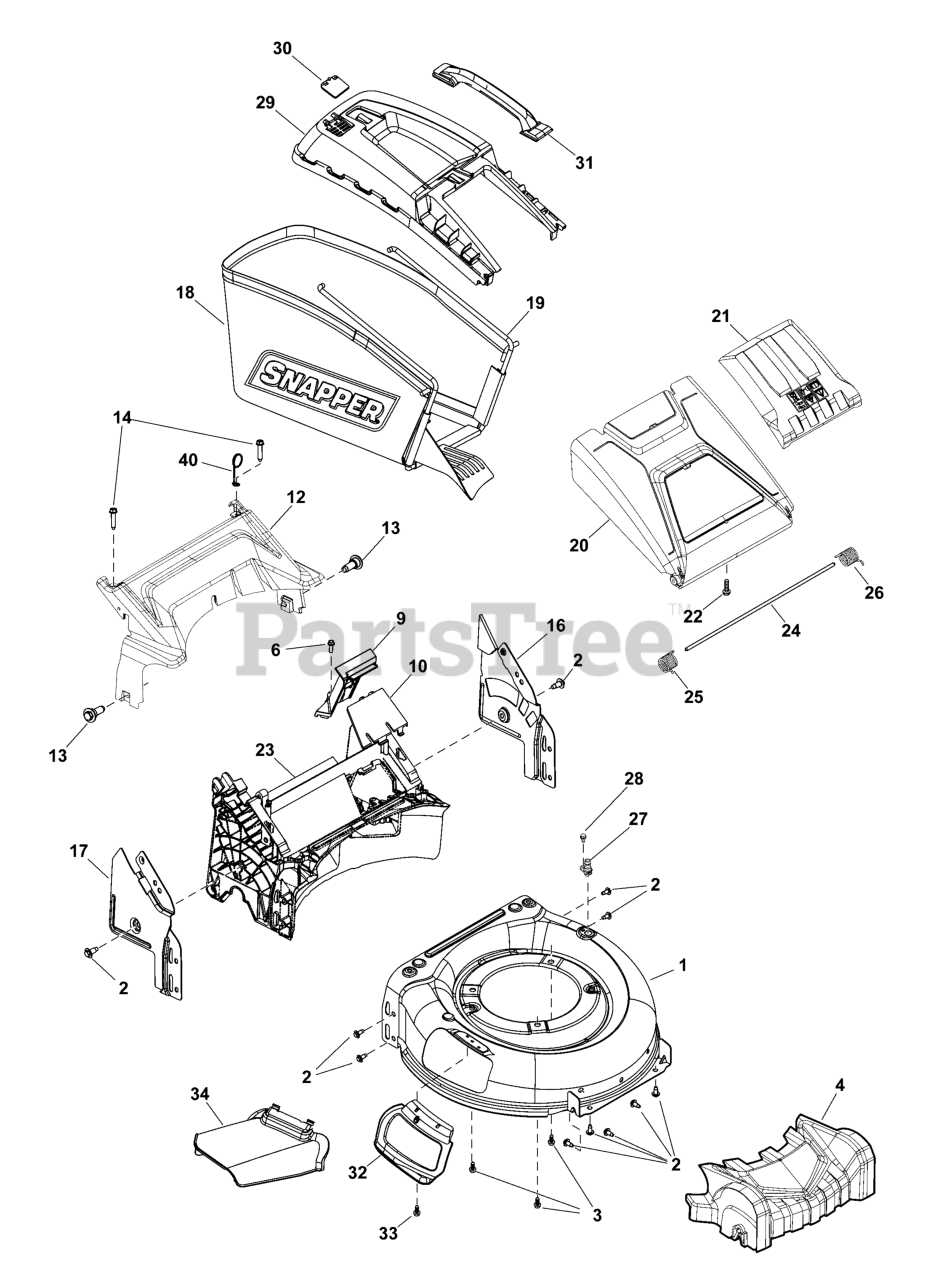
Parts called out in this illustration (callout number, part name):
1	DECK, NSP
2	SCREW, Hex Head
3	SCREW, Engine Mounting, 3/8-16 x 1
4	FRONT COVER, Deck
6	SCREW, 1/4-15X3/4, Self-Tapping, BZ
9	COVER, Rear
10	COVER, Front
12	COVER, Rear
13	SCREW, Hex Head
14	SCREW, 1/4-15 x 1-1/4
16	SUPPORT, Handle, LH
17	SUPPORT, Handle, RH
20	REAR FLAP
21	COVER, Gray
22	SCREW #10-16 x 3/4
23	GUIDE, Rear
25	TORSION SPRING, RH
26	TORSION SPRING, LH
27	NOZZLE, Wash
28	SCREW, 1/4-20 x 1/2
29	COVER, Bagger
30	INDICATOR, Full Bag
32	MULCHING FLAP
33	CAPSCREW, 1/4-20 X 1/2
34	DEFLECTOR
40	CABLE GUIDE
